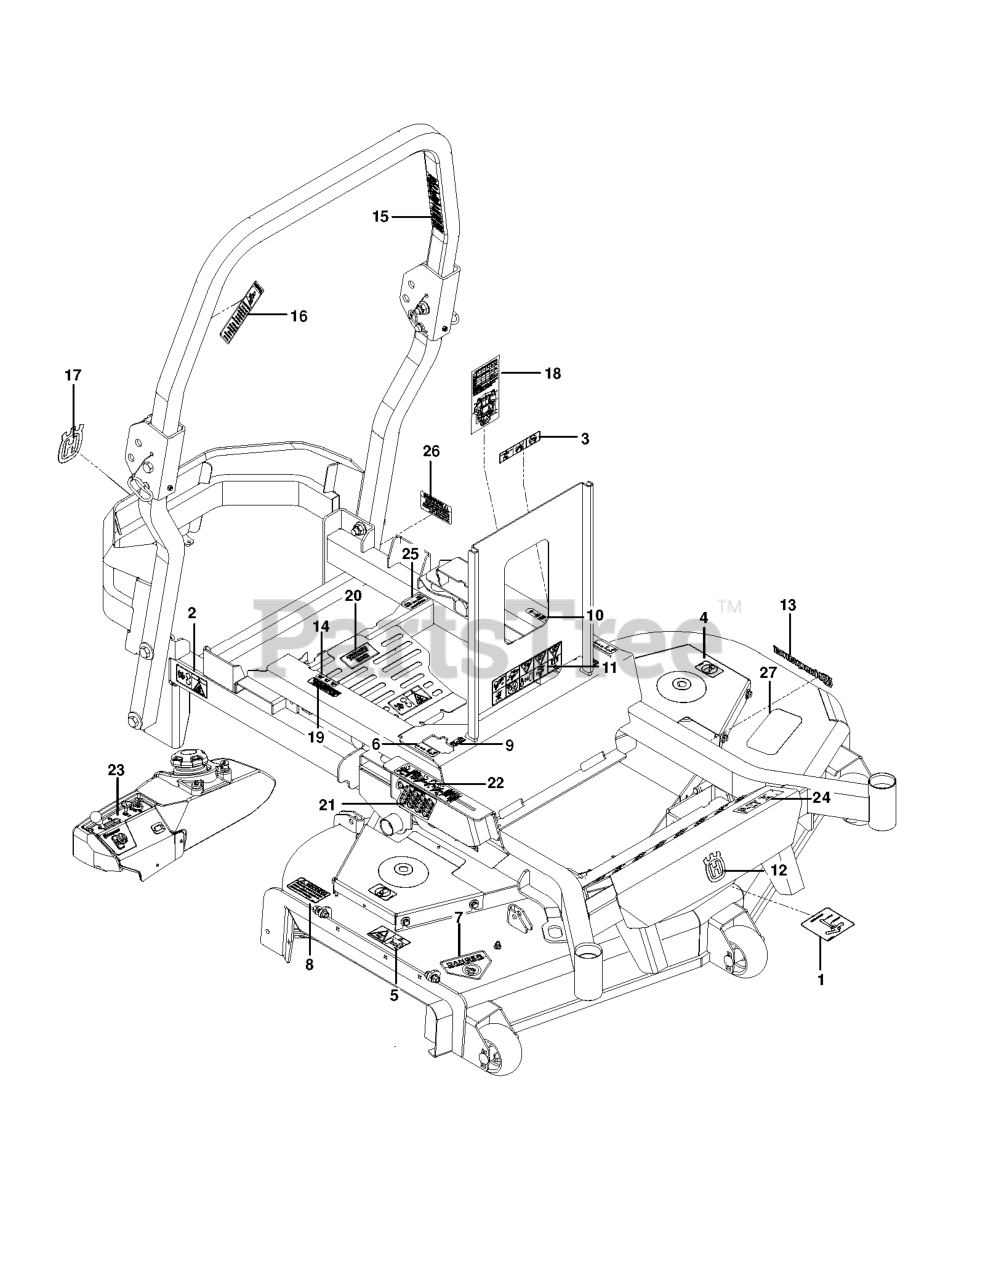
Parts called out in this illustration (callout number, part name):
1	DECAL, BELT ROUTING
2	DECAL, BELT DRIVE
3	EURO DECAL-BATTERY WARNIN6
4	DECAL, NO STEP
5	DECAL, EURO SEVERING
6	DECAL, MOTION CONTROL
7	DECAL, CPSC
8	DECAL, CAUTION
9	DECAL, F.S.T.
10	DECAL, PARK BRAKE
11	DECAL, WARNING
12	DECAL.AUGER.HUSQ.CROWN.SNOW
13	RP.DECAL.BADGE.170MM.TEXTLOGO
14	DECAL, FUSE
15	DECAL, ROPS
16	DECAL, ROPS, WARNING
17	DECAL, CROWN H, 110MM
18	DECAL, SERVICE
19	DECAL, WARNING SPARK ARRESTOR
20	HG_DECAL, ZT-3400
21	DECAL, HEIGHT
22	DECAL, RELEASE LEVER
23	DECAL, CONTROL, GAS
24	DECAL P-ZT 48
25	DECAL, FUEL
26	DECAL, PROP. 65
